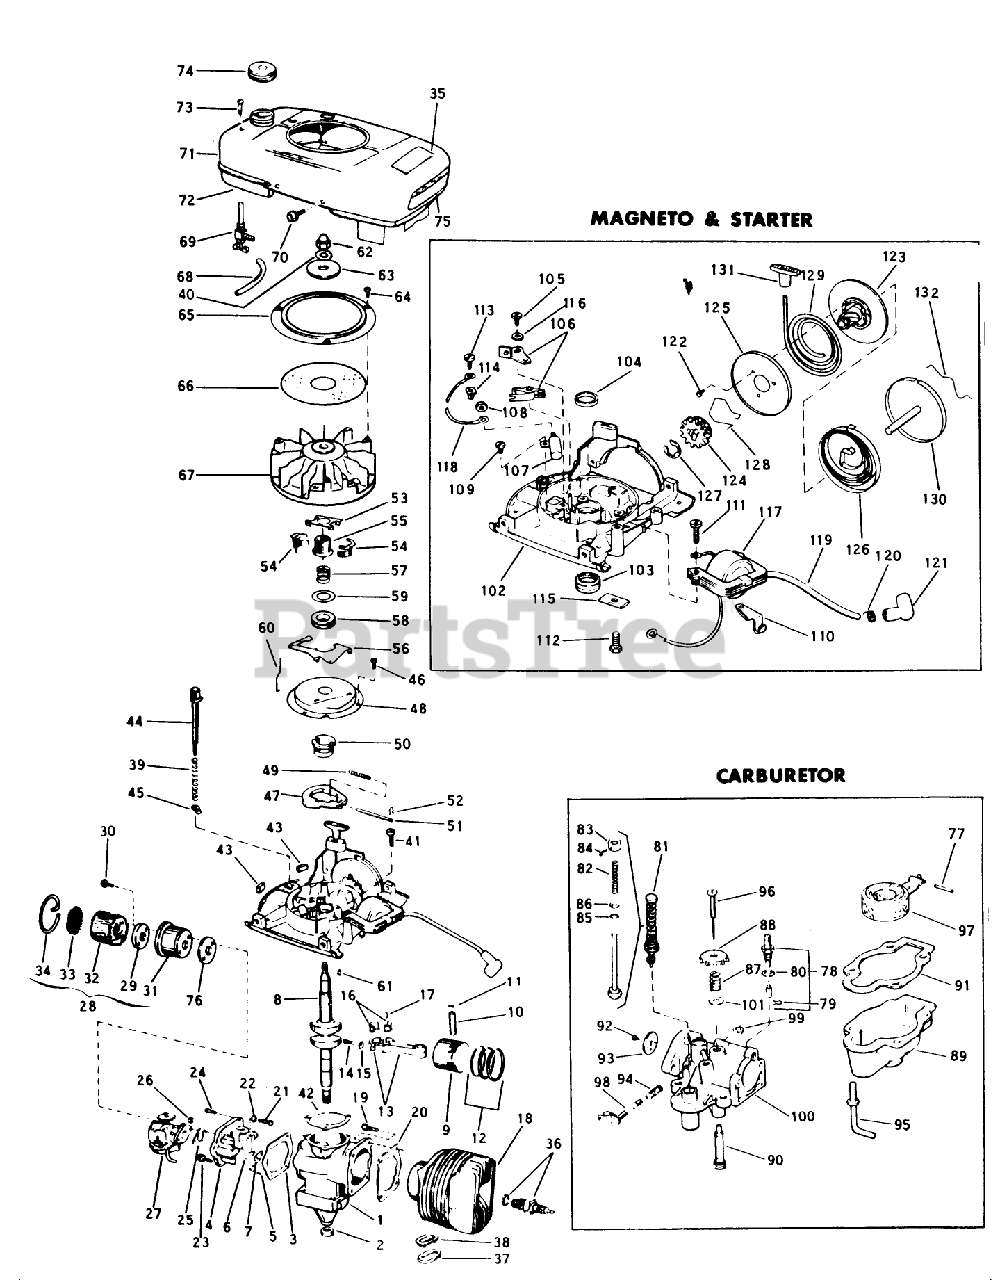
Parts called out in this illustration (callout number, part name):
7	PLATE-BACKUP, REED
11	RING-RETAINING
16	LINER ASM
20	GASKET S
23	SCREW S
24	SCREW S
25	GASKET S
26	STOP NUT
29	BACK-UP PLATE
30	SCREW S
32	ELEMENT
36	Spark Plug
37	GASKET S
39	SPRING S
41	GASKET S
42	GASKET S
46	SCREW S
47	FLYWEIGHT S
48	DUST COVER S
49	SPARK ADV. SPRING S
50	SPARK ADV. S
51	PIN,SPARK ADV. S
52	SPARK ADJ. SPRING
55	COLLAR S
56	LEVER-GOVERNOR S
58	THRUST COLLAR S
65	Ring-Flywhl. Scrn.
69	VALVE&SCREEN SM
70	SCREW S
81	PRIMER AY S
82	Spring-Compression
87	Spring-Ndl. Adj.
91	GASKET S
93	THROTTLE DISC S
96	NEEDLE AY. S
98	THROTTLE LEVER S
99	RING GRIP S
103	BRG. & SEAL AY.
106	BREAKER AY. S
112	SCREW S
114	NUT - CLIP
119	LEAD AY. S
121	Cover-Rubber
124	STARTER PINION S
126	SPRING S
128	STARTER SPRING S
132	SPRING S
